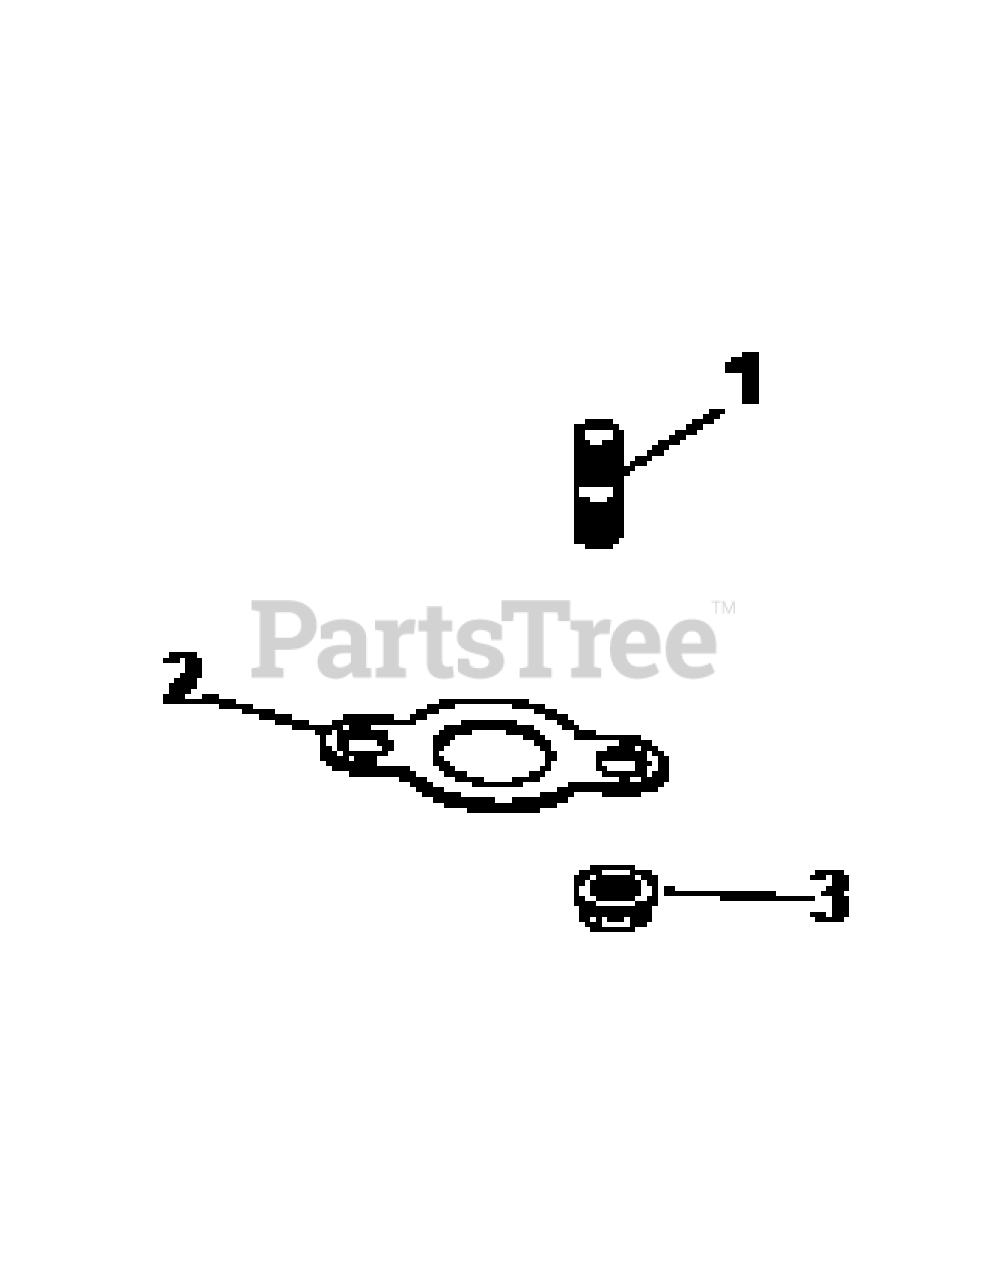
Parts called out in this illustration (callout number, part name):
1	Stud (M8 x 1.25 x 33)
2	Exhaust Gasket
3	Muffler Mounting Nut (M8 x 1.25)
